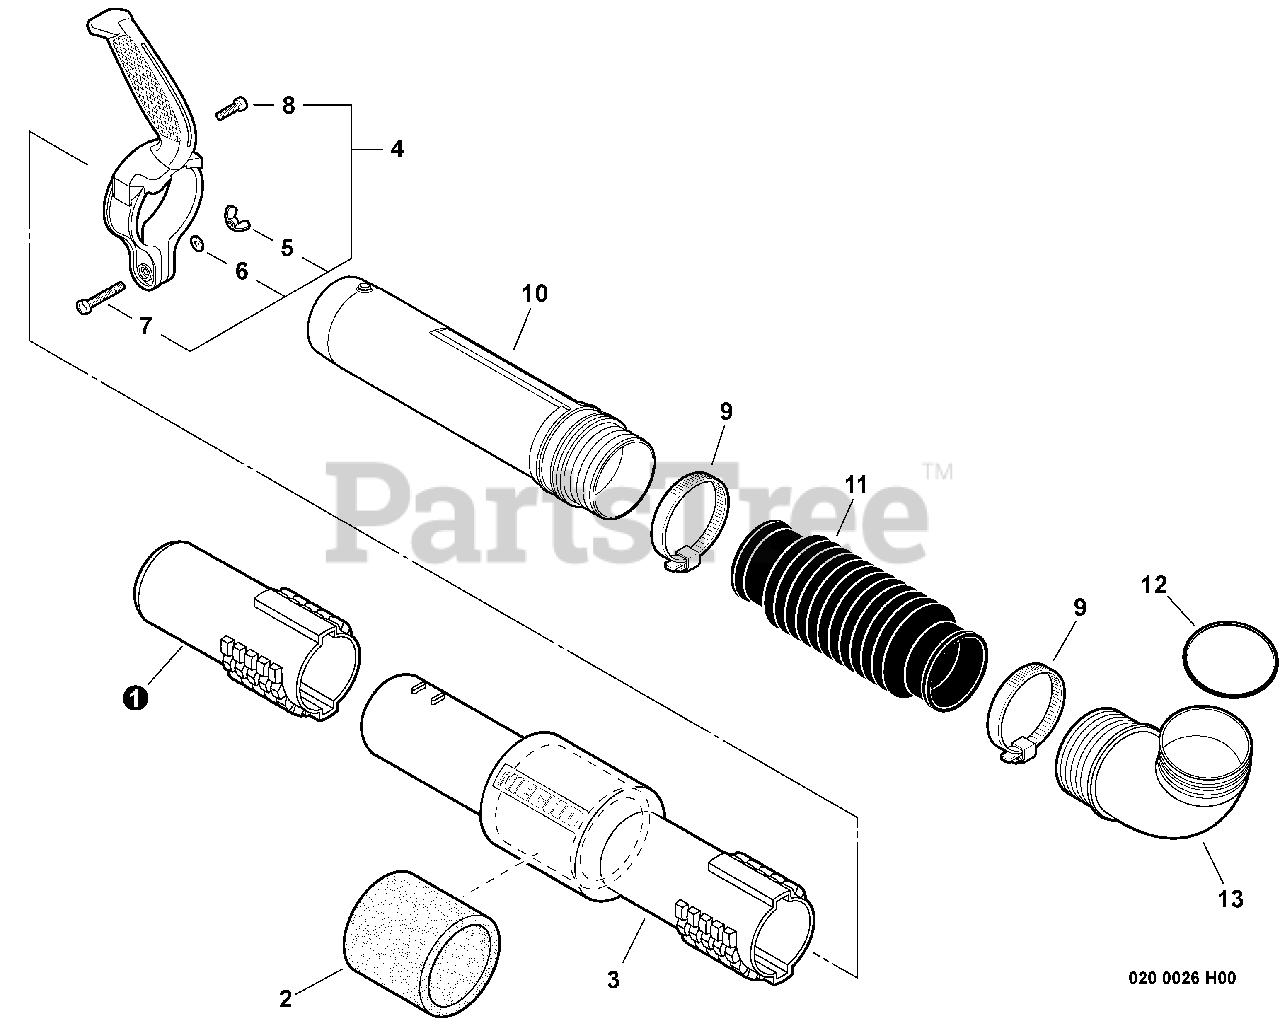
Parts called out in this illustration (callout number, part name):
1	TUBE, BLOWER - NOZZLE
2	PAD, FOAM
3	TUBE, BLOWER - STRAIGHT
4	HANDLE KIT - BLOWER TUBE
5	NUT, WING 6
6	WASHER 6.5×11.5×0.8
7	BOLT 6×25
8	BOLT, TORX 4×16
9	CLAMP - BAND
10	TUBE, BLOWER - SWIVEL
11	TUBE, BLOWER - FLEXIBLE
13	TUBE, BLOWER - ELBOW
